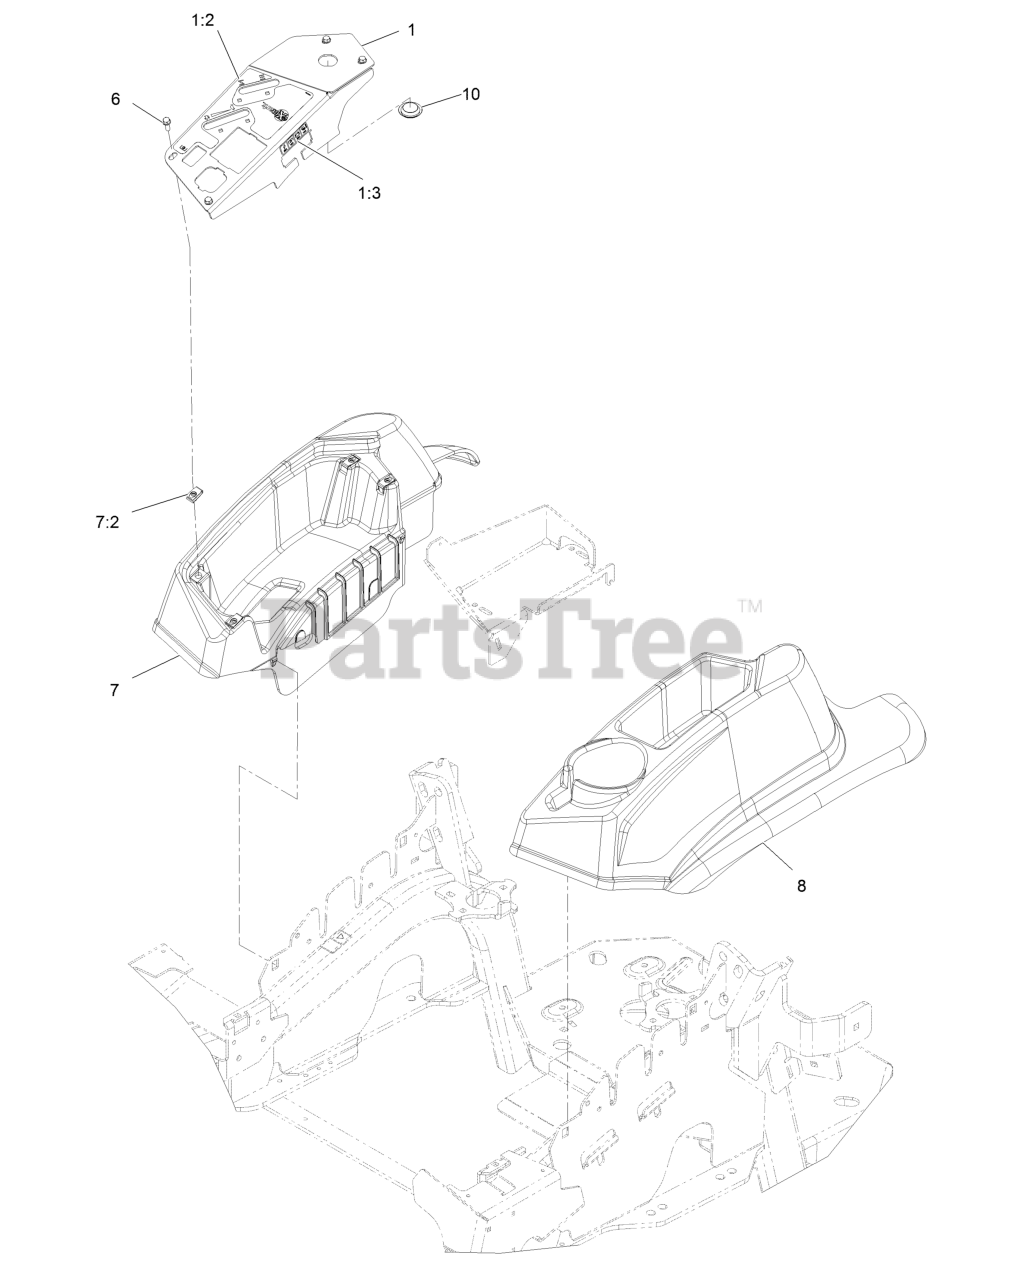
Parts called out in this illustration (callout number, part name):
1	Console,Panel W/Decal
1:2	Decal-Control Panel Non-Efi
1:3	Decal-Fuses
6	Screw-Machine 1/4-20 X 3/4
7	Console,RH As ASM
7:2	Nut-Retainer-Panel 1/4-20
8	Console, LH As
10	Plug-Plastic
